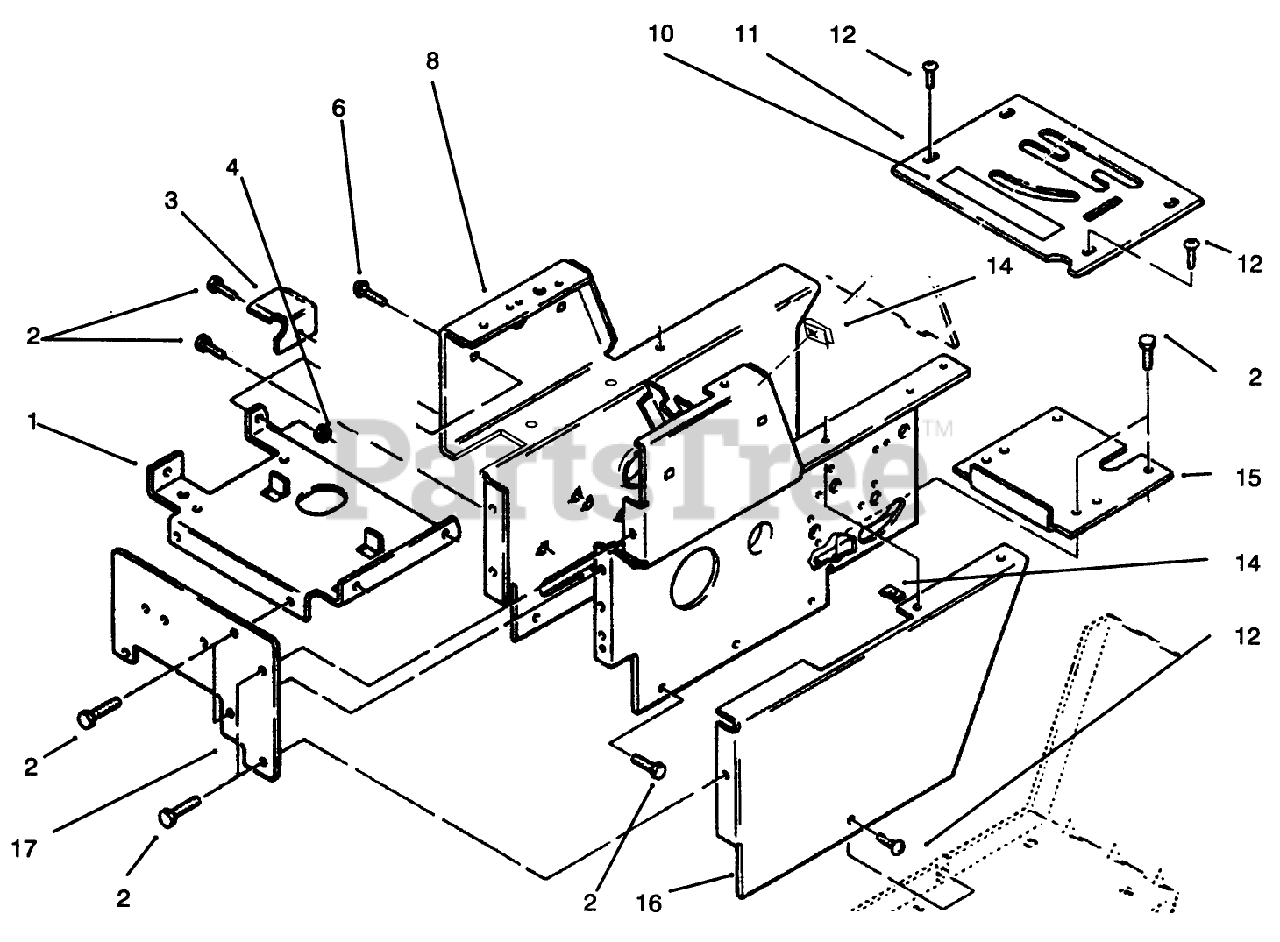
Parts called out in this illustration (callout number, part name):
10	DECAL-DANGER
11	SHIFT PLATE/DECAL ASM
12	SCREW-PPH
